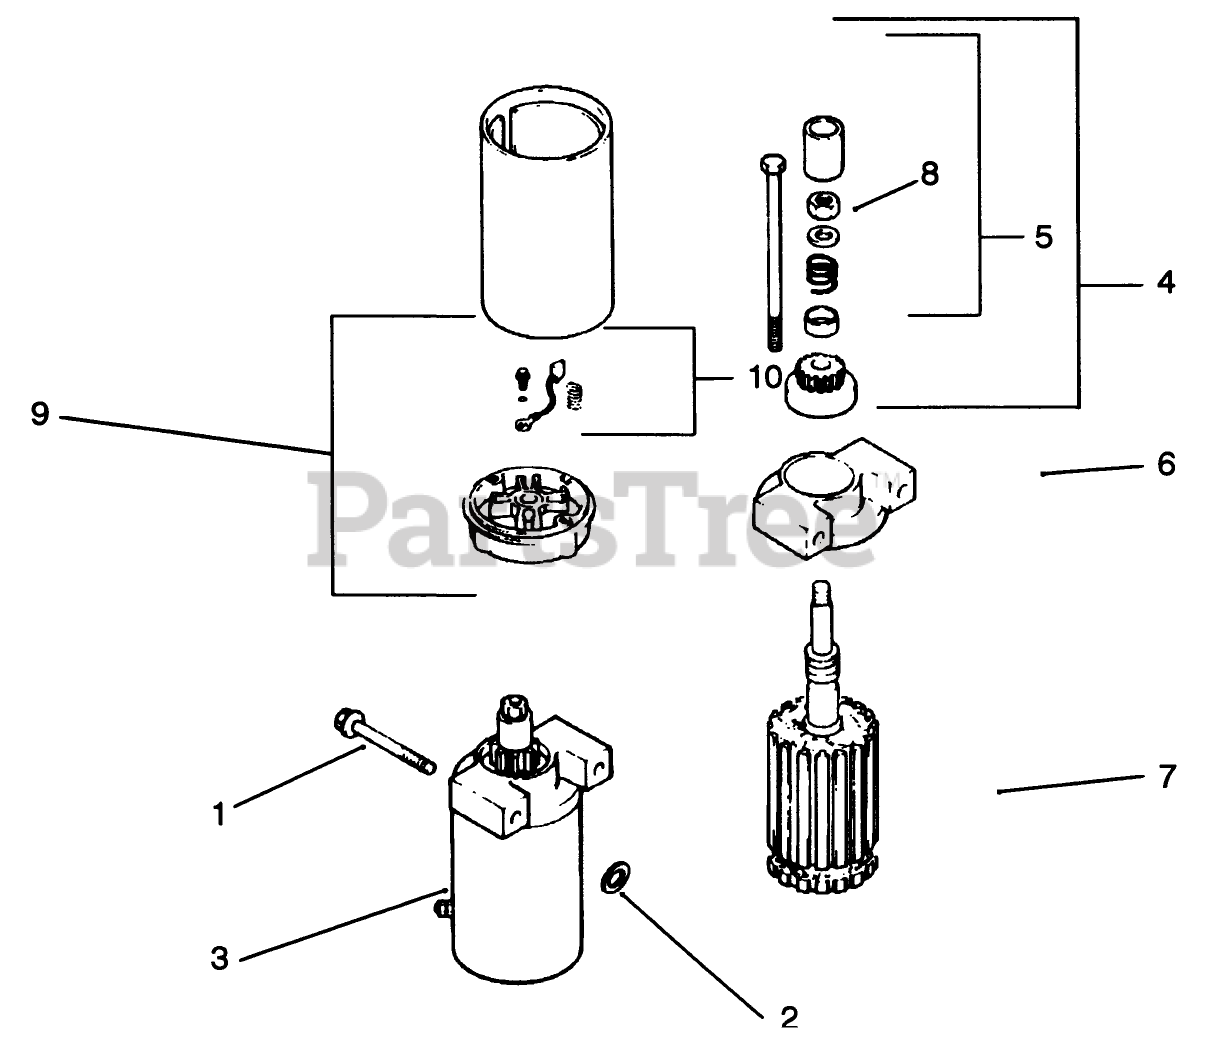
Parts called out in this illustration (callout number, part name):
2	Washer (Only On: 72042, 72063, 72062, 72043)
3	Starter (Incl. Ref. #4-10)
4	Kit-Drive INC 7 (Only On: 72042, 72063, 72062, 72043)
5	Kit-Drive Parts (Only On: 72042, 72063, 72062, 72043)
6	Cap-Drive End
7	Armature (Only On: 72042, 72063, 72062, 72043)
8	Screw-HF (Only On: 72042, 72063, 72062, 72043)
9	Cap-Commutator End
10	Kit-Brush
